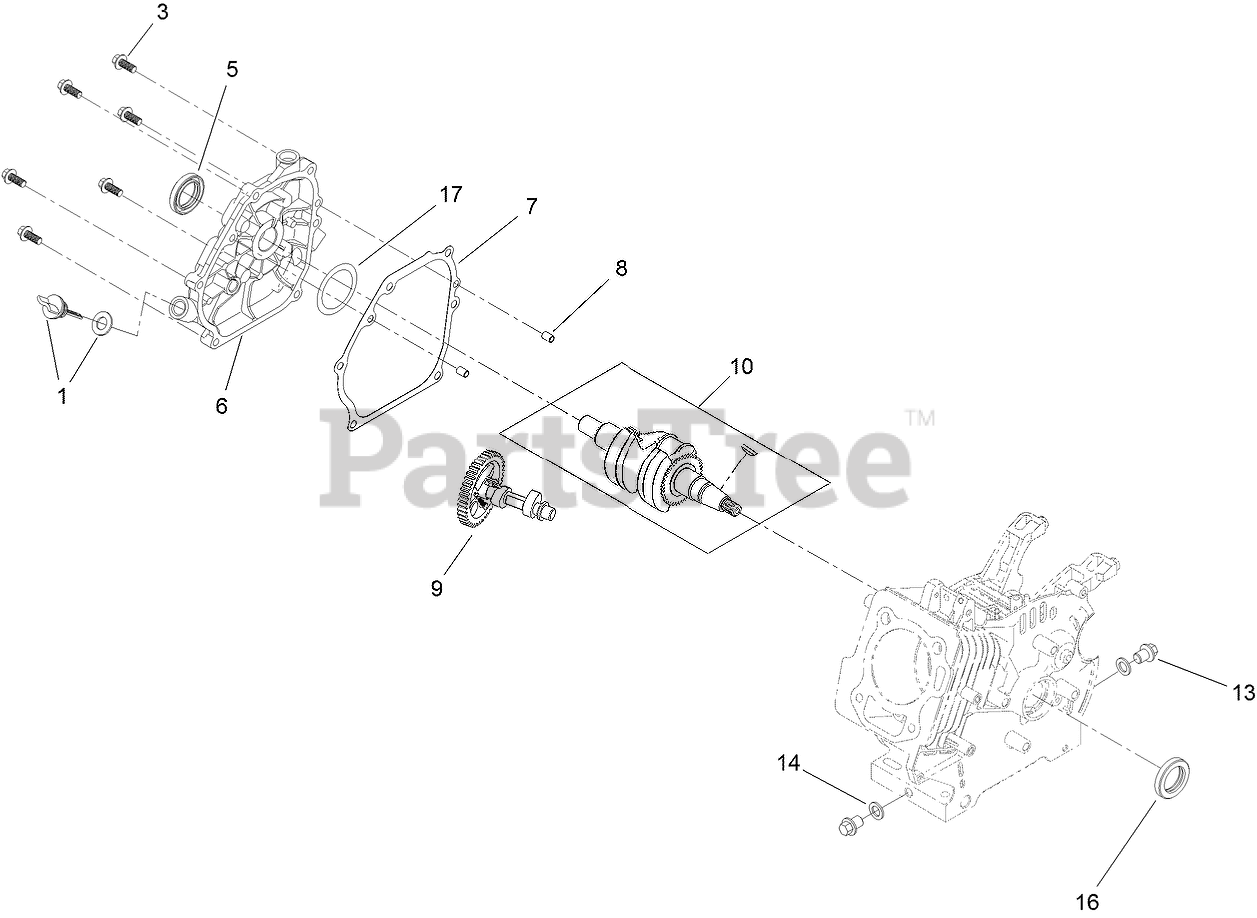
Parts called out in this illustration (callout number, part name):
1	DIPSTICK AND O-RING KIT
3	SCREW-HHF
5	SEAL-OIL
6	COVER-CRANKCASE
7	GASKET-COVER, CRANKCASE
8	PIN-DOWEL
9	CAMSHAFT ASM
10	CRANKSHAFT ASM
13	SCREW-HHF
14	WASHER-PLAIN
16	SEAL-OIL
17	WASHER-THRUST
